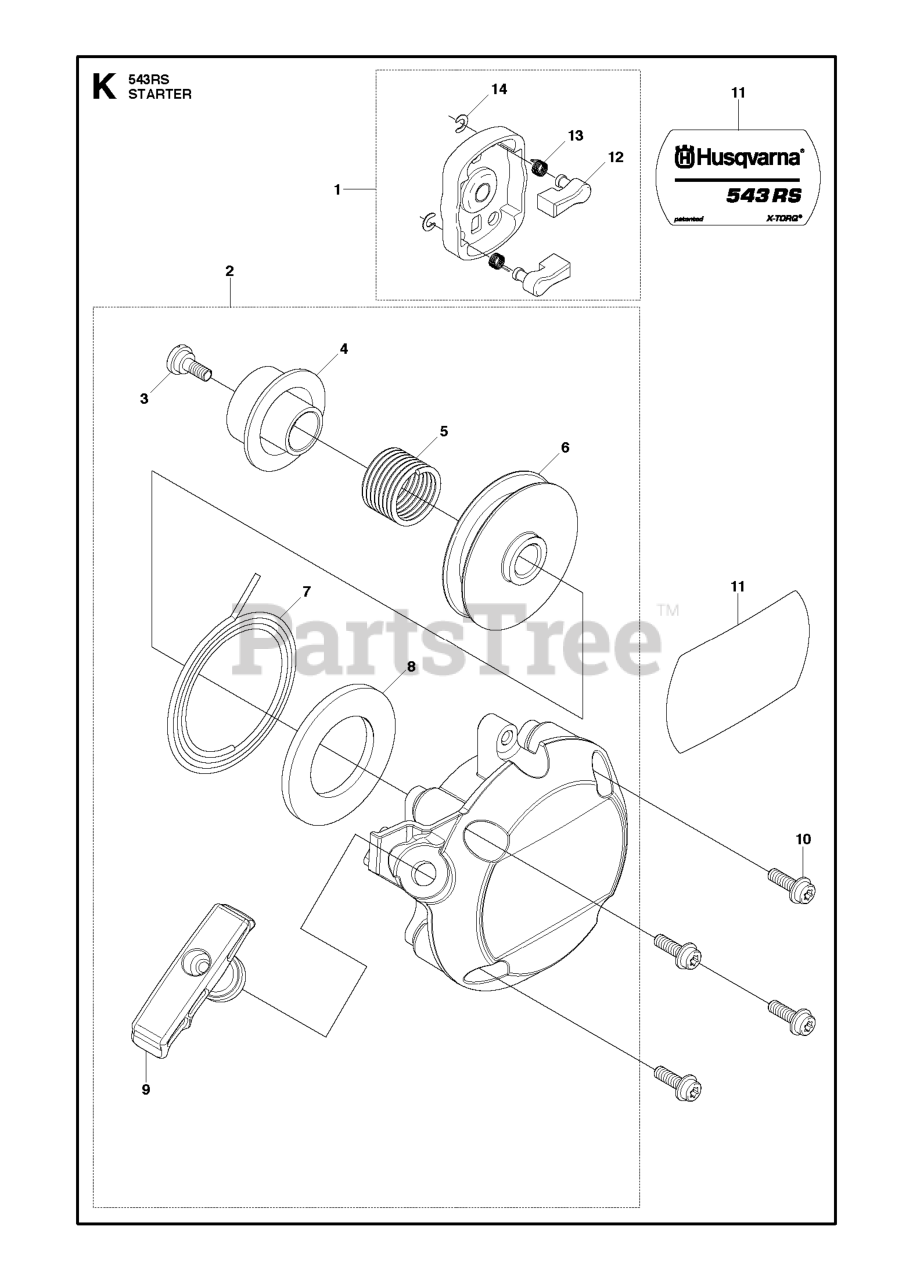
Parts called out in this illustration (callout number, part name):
1	PULLEY ASSY
4	PLATE, CAM
5	SPRING, DAMPER
11	DECAL RECOIL
